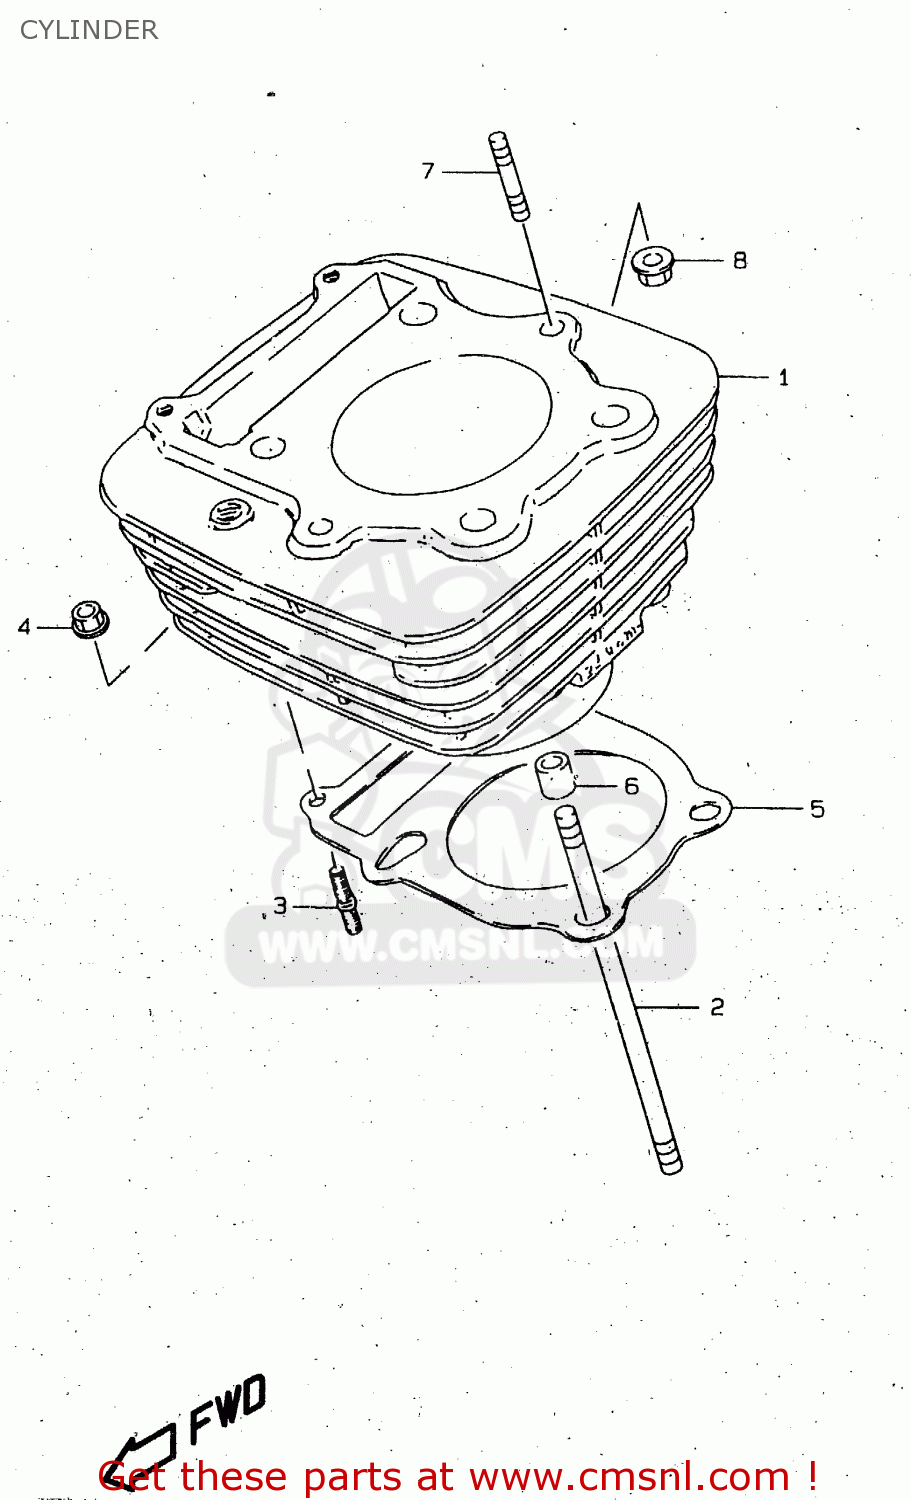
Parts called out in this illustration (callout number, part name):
1	CYLINDER
2	BOLT,STUD
3	STUD 6X20
4	NUT
5	GASKET,CYLINDER (NAS)
6	PIN
7	BOLT,STUD
8	NUT
